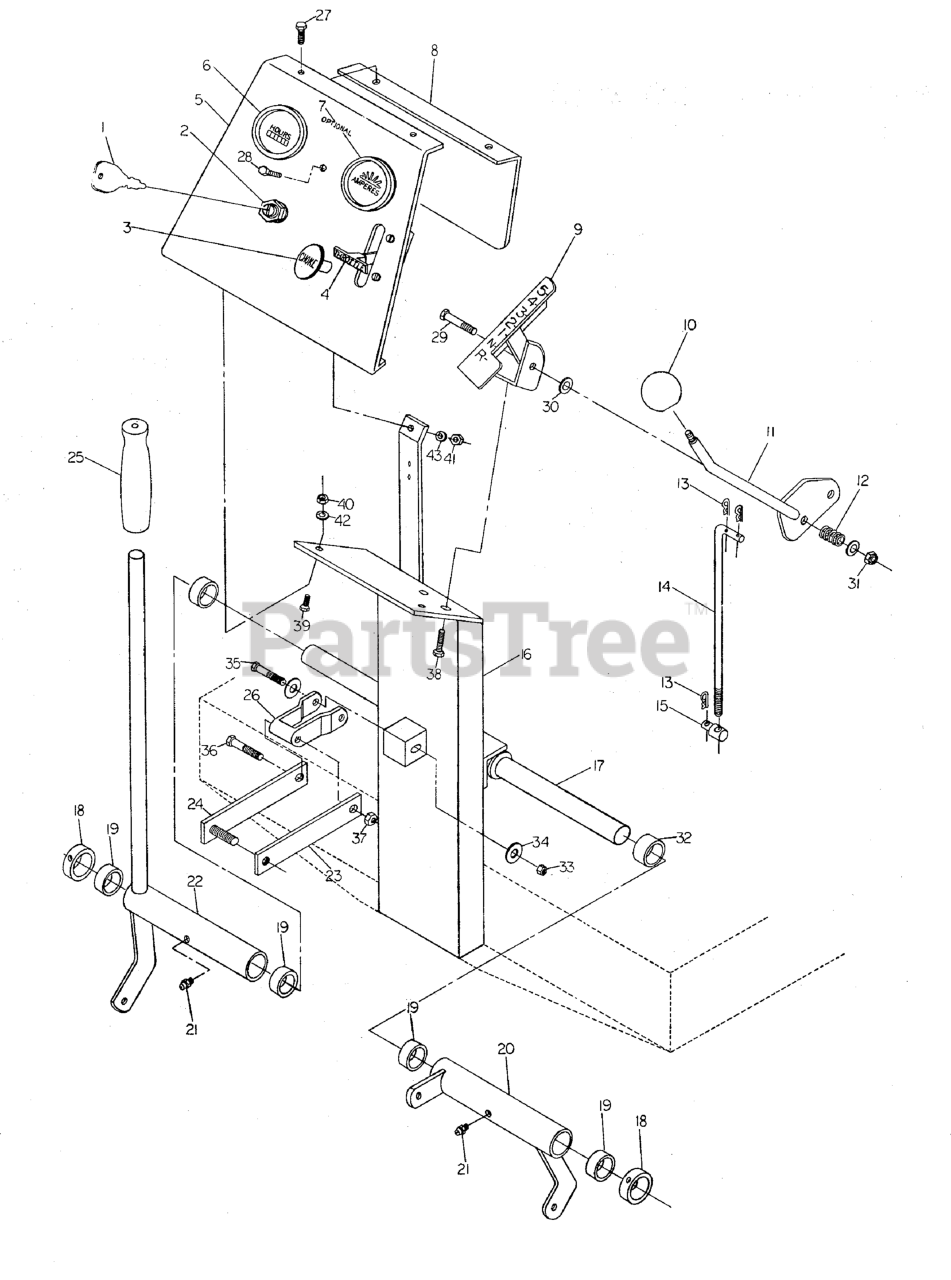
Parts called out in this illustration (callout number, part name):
1	Ignition Key
2	SWITCH, Ignition
3	CABLE, CHOKE CONTROL, 45
4	CABLE, Throttle, 38"
5	Control Panel
6	HOUR METER
7	Ammeter
8	Control Panel Cover
9	Shifter Guide Weldment
10	Black Knob
11	Shifter Handle Weldment
12	SPRING, Compression
13	HAIRPIN CLIP
14	Shifter Adjustment Rod
15	Linkage Adjuster
16	Upright Support Weldment
17	3/4" Diameter Shaft 21" Long
18	COLLAR, 3/4" Set
19	BUSHING
20	Transmission Bell Crank Weldment
21	GREASE FITTING
22	Blade Engage Weldment
23	Actuator Linkage Arm
24	Actuator Linkage Arm
25	Handle Grip
26	Coupler Link
28	5/16-18 x 1 Hex Head Cap Screw
29	3/8-16 x 2 GD 5 Bolt
30	3/8 Flat Washer
31	3/8-16 Lock Nut
32	BUSHING
33	3/8-16 Lock Nut
34	3/8 Flat Washer
35	5/16-18 x 2-1/4 GD 8 Bolt
36	5/16-18 x 2-1/4 GD 8 Bolt
37	5.16-18 Lock Nut
38	1/4-20 x 1 Hex Head Cap Screw
39	1/4-20 x 3/4 Hex Head Cap Screw
40	1/4-20 Nut
41	5/16 Serrated Flange Nut
42	1/4-20 Lock Washer
43	5/16 Lock Washer
